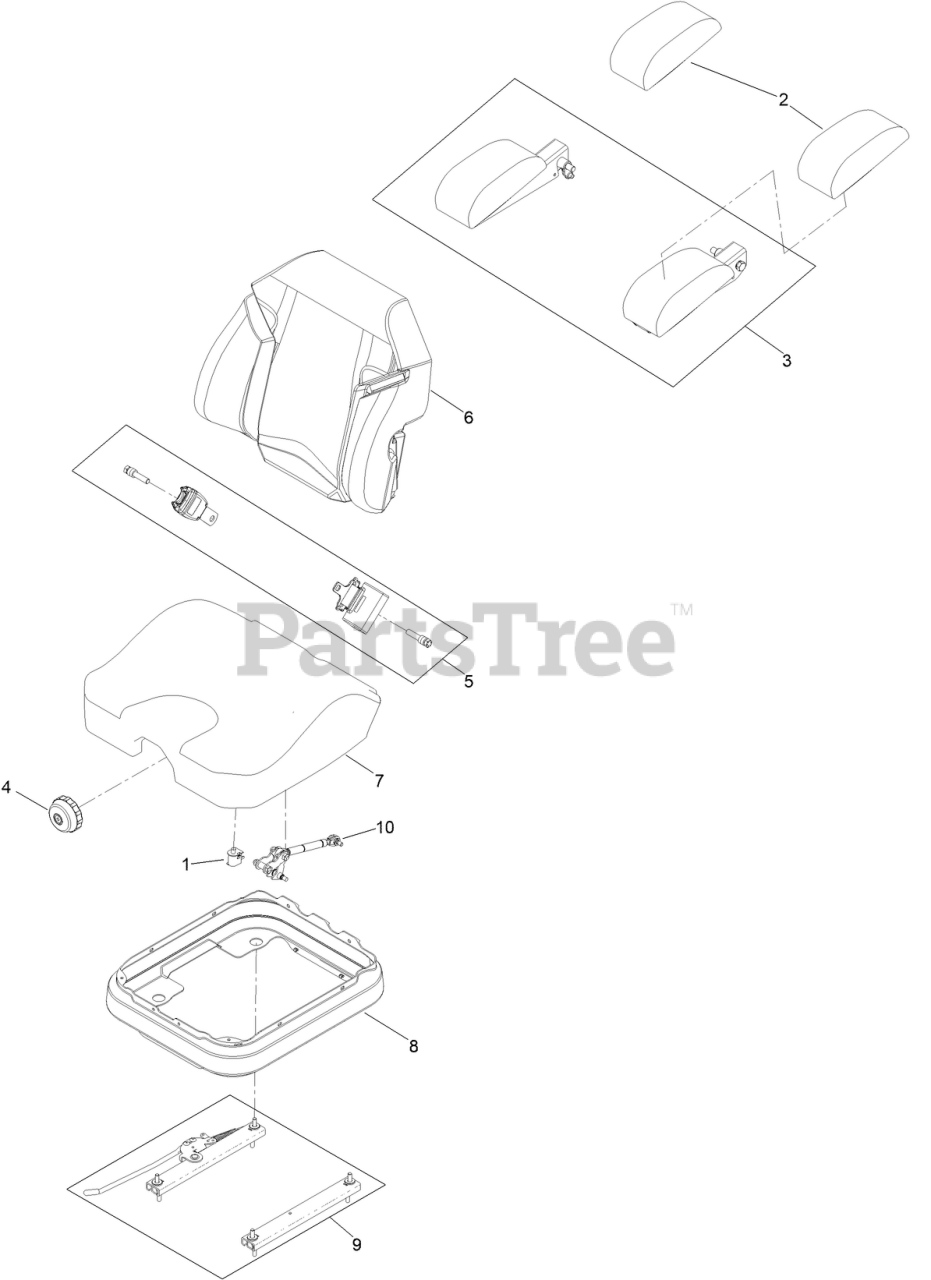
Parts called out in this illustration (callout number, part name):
1	SWITCH-BAIL
2	KIT-ARM REST PADS
3	KIT-ARM REST SET
4	KNOB-ADJUSTER
5	KIT-SEAT BELT
6	COVER-BACK
7	COVER-BOTTOM, SEAT
8	COVER-SUSPENSION BELLOWS
9	SET-SEAT TRACK
10	DAMPER-SEAT
